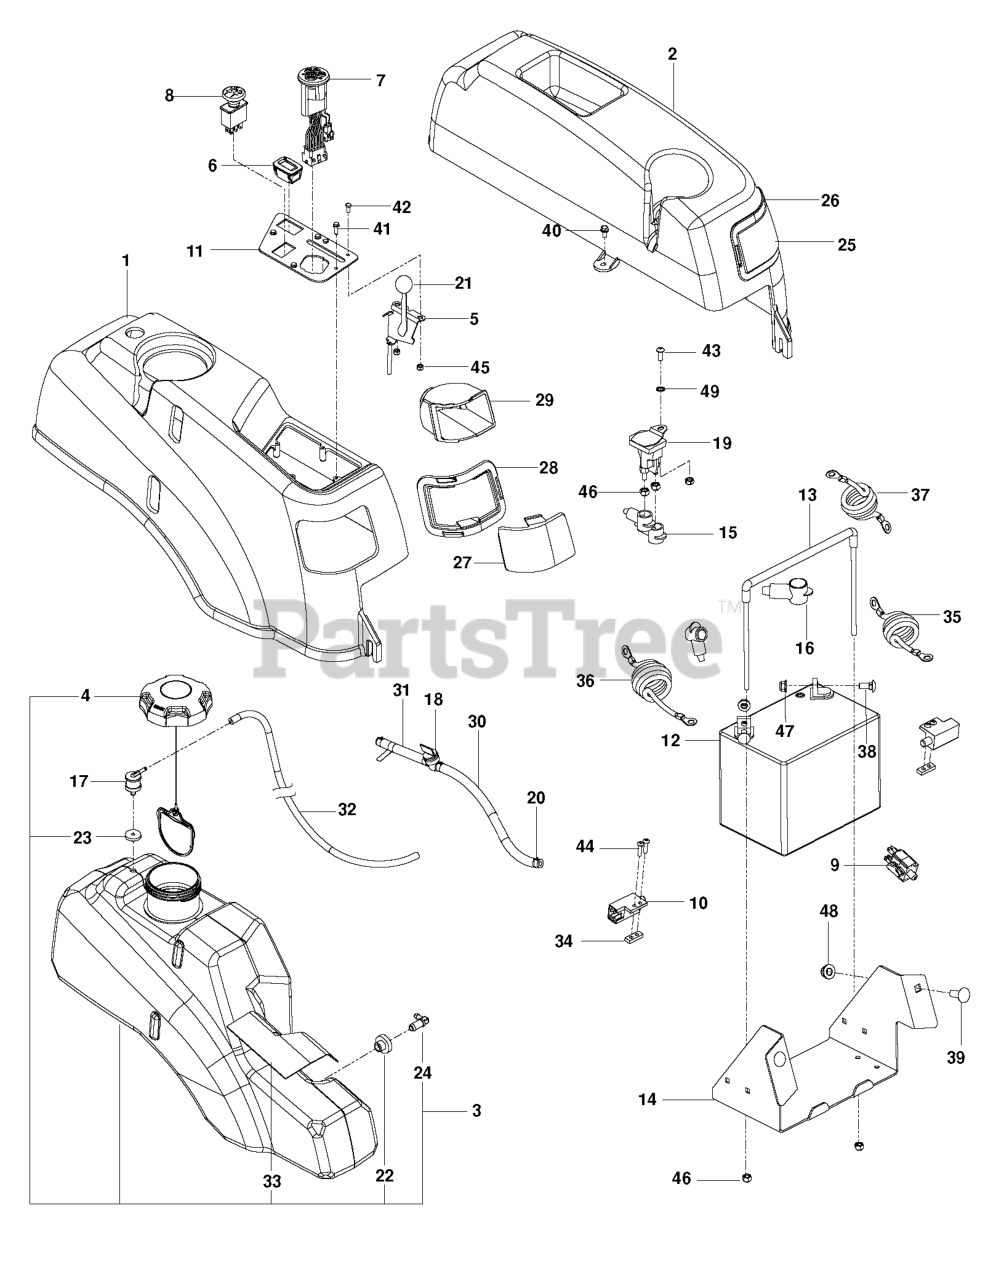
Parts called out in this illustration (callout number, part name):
1	FENDER RT, GRAY
2	FENDER, LT
3	TANK.FUEL.ASSEMBLY.LARGE
4	CAP, FUEL
5	CABLE THROTTLE 39"
6	RP.GUAGE.SRVCMNDR.HRMTR.
7	SMART SWITCH MY14 ZTR RZ
8	RP SWITCH.PTO.8.TERMINAL.RED
9	SWITCH, BRAKE 3P
10	SWITCH INTERLOCKT
11	CONTROL.PLATE X431
12	BATTERY, 12 V 330 AMP
13	BATTERY TIE DOWN ASSEMBLY
14	BOX, BATTERY, BLACK
15	TERMINAL COVER
17	VALVE.FUEL.CHECK
18	FUEL VALVE
19	SOLENOID.W/BRASS.PLUNGER
20	HOSE CLAMP
21	KNOB.ROUND.BALL.BLACK
22	RUBBER GROMMET
23	GROMMET, CHECK VALVE
24	STEM, FUEL TANK
25	LEFT HEADLIGHT LENS
26	LEFT HEADLIGHT RIM GREY
27	RT HEADLIGHT LENS
28	RT HEADLIGHT RIM GREY
29	REFLECTOR, HEADLIGHT RT
30	GAS LINE 10"
31	FUEL LINE 3"
32	HOSE, FUEL, 3/16" X 17-1/4"
33	SHIELD, HEAT
34	TAPPED PLATE
35	CABLE BATTERY POS RZ
36	CABLE.BATTERY.NEGATIVE.RZ
37	CABLE BATTERY POS HARNESS
38	RP BOLT 5/16-18 X3/4 ZN/YEL GR
39	BOLT D
40	SCREW
41	SCR #10-12X3/4 HEX WAS HD ZD
42	HCS #10-24 X 1/2
43	SCR 1/4-20 X 5/8 BTN SKT HD ZD
44	SCR #10-24 X .75 SKT HD BLK
45	NUT 10-24 NYLOC
46	LOCKNUT.NYLOC.1/4-20
47	5/16-18 NYLOC FLANGE NUT
48	NUT 3/8-16 HEX FLG NYLOC ZD
49	WASHER 1/4 INT TOOTH
